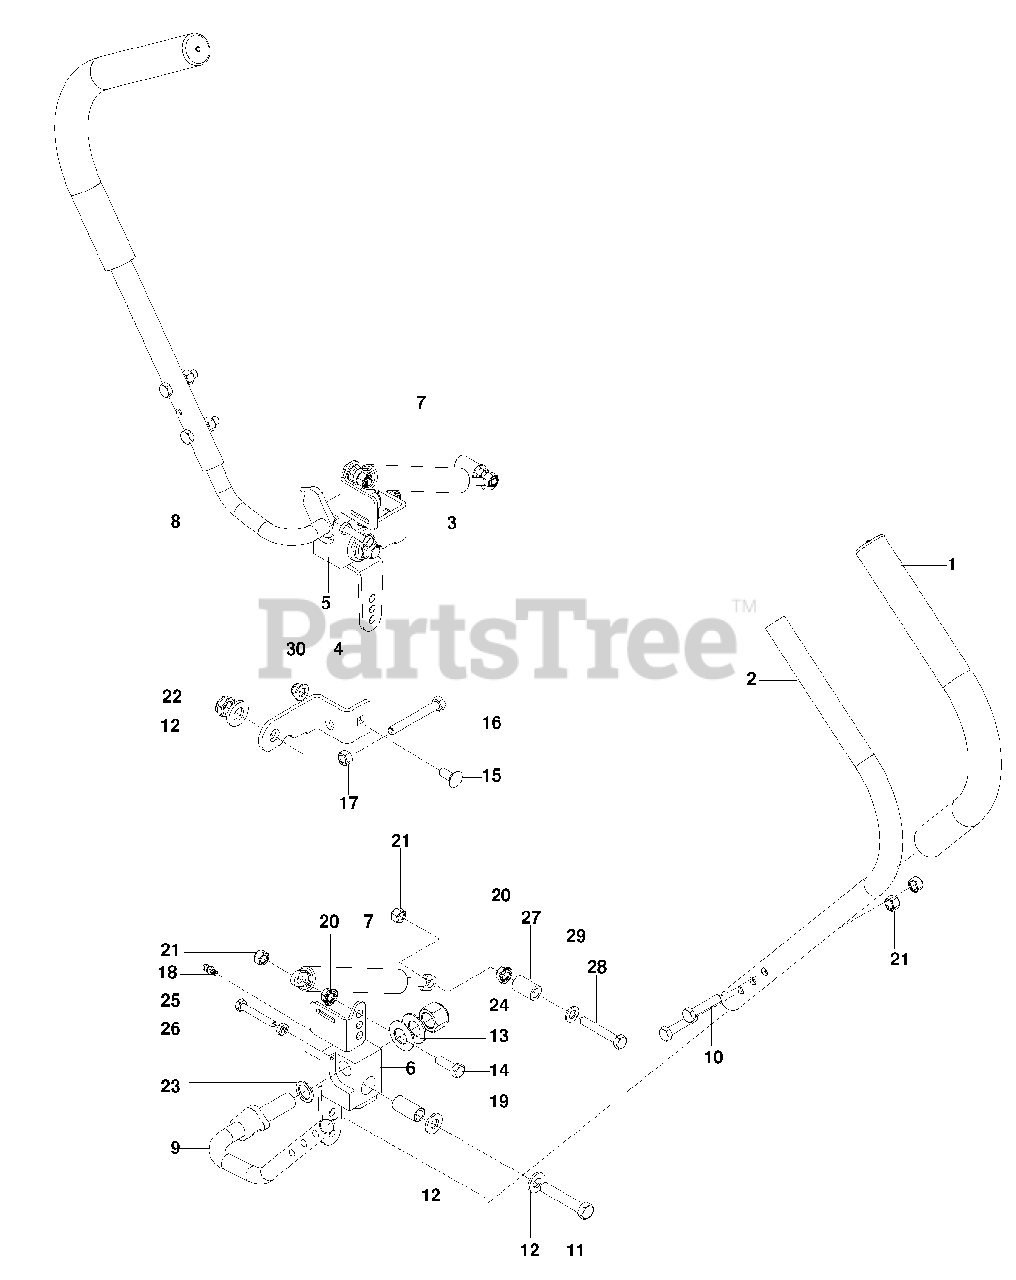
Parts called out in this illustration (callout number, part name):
2	LEVER, UPPER
3	STOP, STEER CNTRL RH
4	STOP, STEER CNTRL LH
8	LOWER LEVER, RH
9	LOWER LEVER, LH
10	HCS 5/16-18 x 1 1/2
11	HCS 1/2-13 x 2 3/4
12	WASHER 1/2 SAE
13	WASHER 5/8 BELLEVILLE
14	HCS 5/16-18 x 1
15	RHSNB 5/16-18 x 3/4
16	BOLT, HEX 5/16-18 x 2 1/2 TPBLT
17	NUT, 5/16-18 HEX
18	ZERK
19	BUSHING 1/2 ID x 3/4 OD
20	NUT 5/16-18 HEX WHIZLK
21	NUT 5/16-18 HEX NYLOC
22	NUT 1/2-13 JAM NYLOC GR 2
23	WASHER, SPECIAL
24	NUT 5/8-11 NYLOC
25	HCS 1/4-20 x 1 3/4
26	NUT 1/4-20 JAM
28	HCS 5/16-18 x 2
29	WASHER 5/16 SAE FLT
30	NUT 5/16-18 FLG HEX NYLOC
